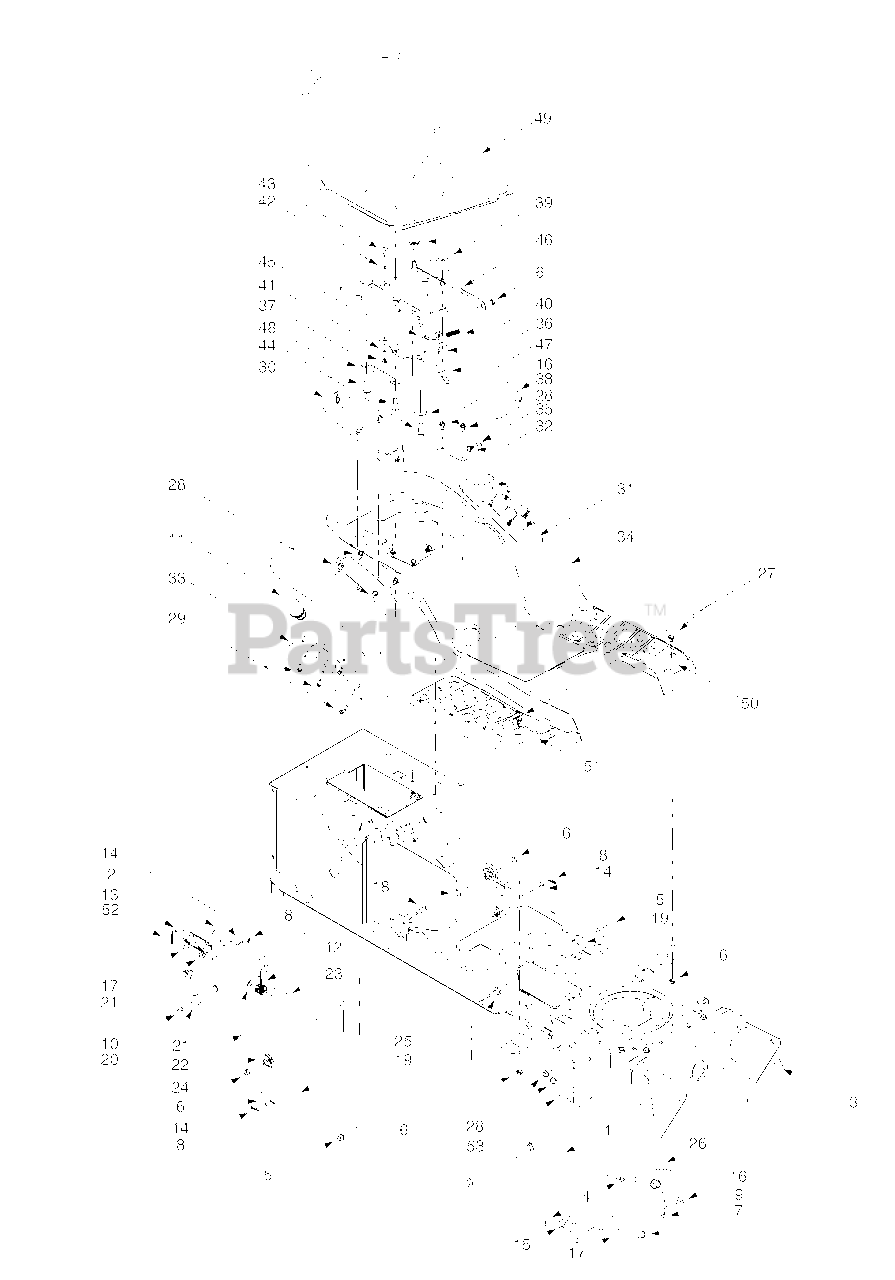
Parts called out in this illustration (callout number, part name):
3	Clevis Pin, .5 x .78
4	Hex Nut, 1/2-13
5	Flange Lock Nut, 3/8-16
6	Flange Lock Nut, 5/16-18
7	Hex Nut, 1/2-13
8	Internal Cotter Pin
9	Internal Cotter Pin
12	Torsion Spring
13	Lift-assist Spring, 1.15 x 5.99
14	Flat Washer, 5/16
15	Lock Washer, 1/2
16	Flat Washer, .31 x 1.062 x .134
17	Flat Washer, .51 x 1.12 x .06
18	Hex Cap Screw, 5/16-18 x .62
19	Shoulder Screw, 3/8-16
20	Hex Flange Bearing
21	Snap Flange Bearing
22	Lift Cable, 16.16
23	Lift Handle
24	Roller Pulley
27	Carriage Bolt, 5/16 x .62
28	Self-tapping Screw, 5/16-18 x .625
29	Self-tapping Screw, 1/4-15 x .75
30	Lift Lever Cover
31	Shift Lever Cover w/ Cup Holder
32	Shoulder Screw, .437 x 1.62
36	Screw, #10-16 x .375
37	Hex Flange Lock Nut, 1/4-20
38	Seat Adjuster Grip
40	Compression Spring, .41 x 1.5
41	Spring Washer, .265 x .562 x .025
42	Flat Washer, .344 x .62 x .03
43	Shoulder Screw, .340 x .285,1/4-20
44	Shoulder Screw, .50 x .50, 3/8-16
48	Seat Adjustment Selector
49	High Back Seat, Black
